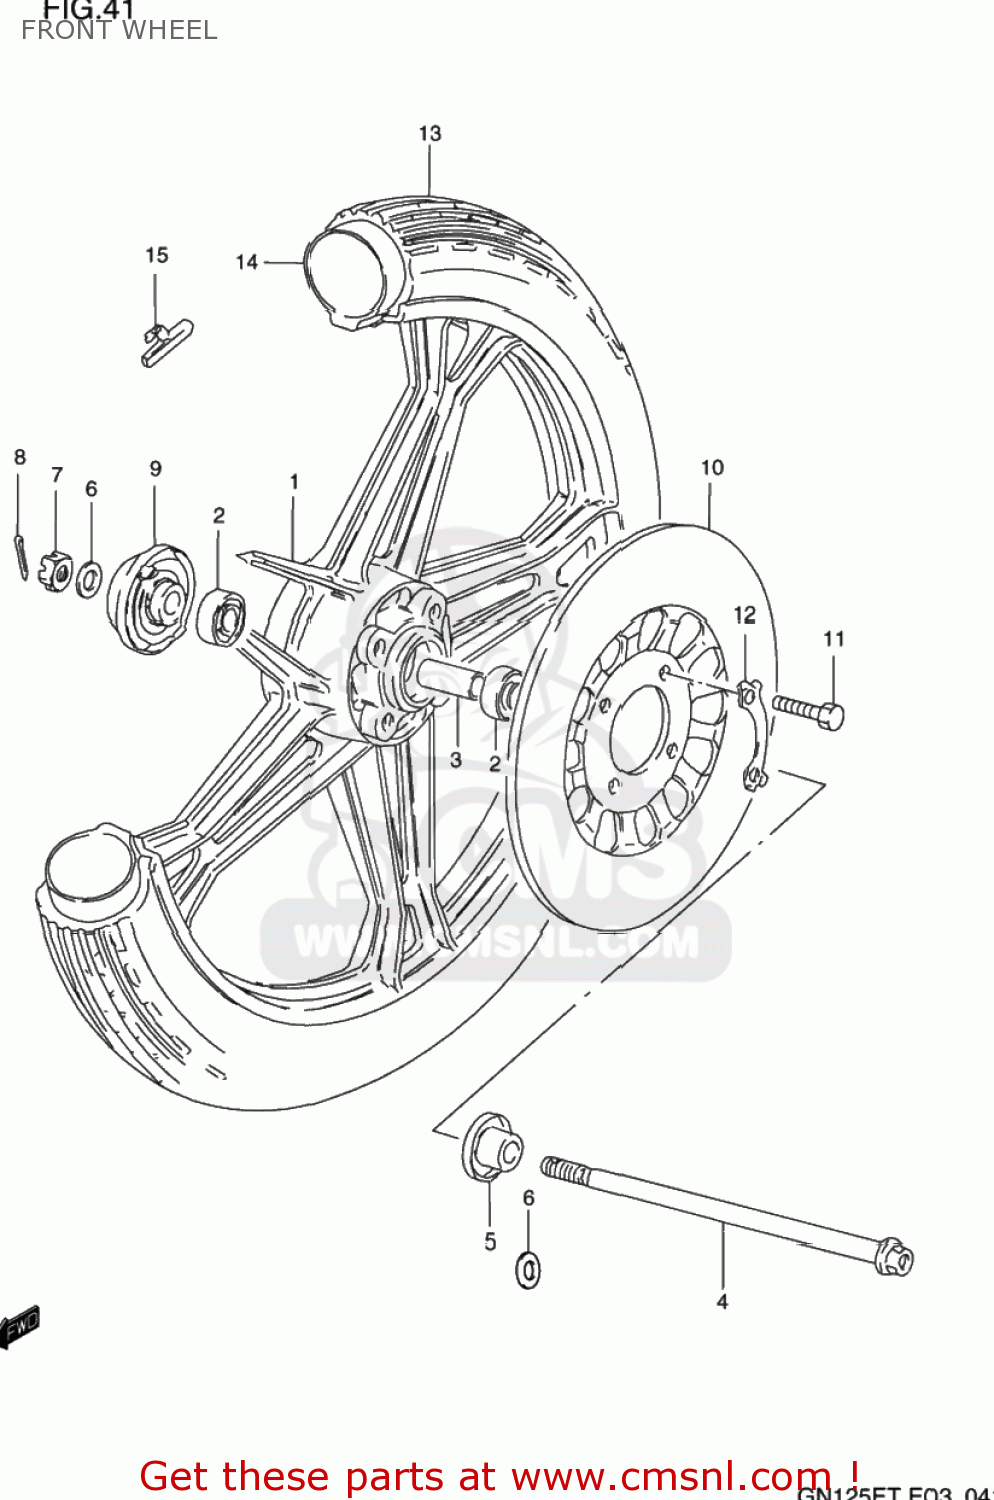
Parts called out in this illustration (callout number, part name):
1	WHEEL,FR(1.60X18)
2	BEARING
3	SPACER (12.6X19X52)
4	AXLE,FR
5	SPACER,FR AXLE,L
6	WASHER
7	NUT
8	COTTER PIN
9	BOX ASSY,SPEEDOMETER GEAR
10	DISC,FR BRAKE
11	BOLT(8X30)
12	WASHER
13	TIRE,FRONT
14	TUBE,INNER
15	BALANCER,WHEEL
